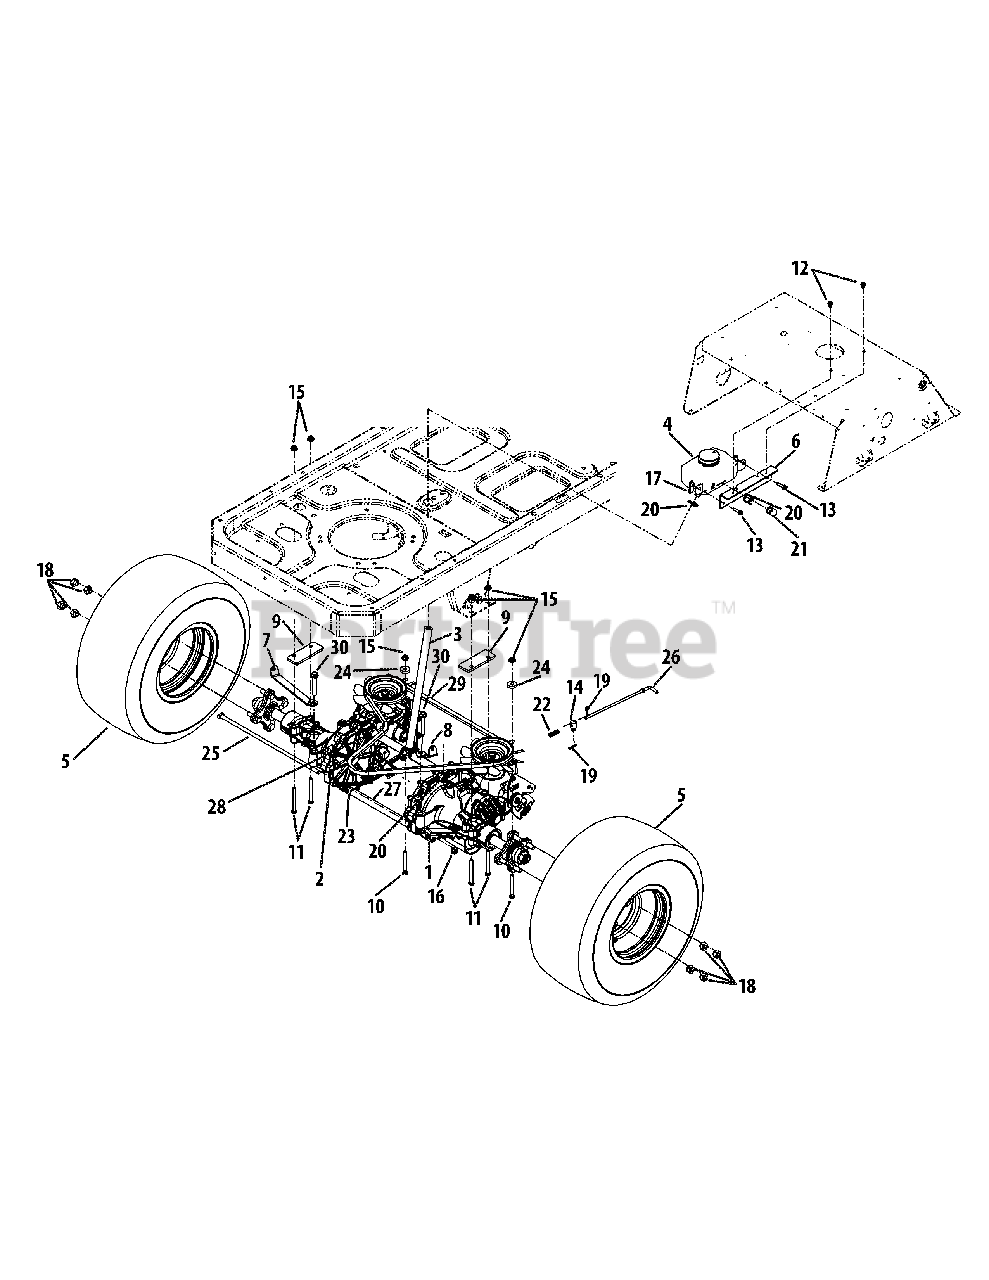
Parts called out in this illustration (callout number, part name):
1	Transmission Assembly (RH)
2	Transmission Assembly (LH)
4	Expansion Tank Assembly
5	Wheel Assembly, 20 x 10 x 8
5	Rim Assembly, 8.0 x 6.19 x 4
5	Tire, 20 x 10 x 8
5	Air Valve
6	Expansion Tank Bracket
7	Transmission Brace (LH)
8	Transmission Brace (RH)
9	Transmission Spacer
10	Hex Screw, 5/16-18 x 2.75
11	Hex Screw, 5/16-18 x 3.00
12	Screw, 1/4-20 x .500
13	Screw, 1/4-20 x 1.000
14	Ferrule, .325 x .312
15	Flange Lock Nut, 5/16-18
16	Flange Lock Nut, 3/8-16
17	Speed Nut, 1/4-20
18	Lug Nut, 7/16-14
19	Bow-Tie Cotter Pin
20	Hose Clamp, 1/2"
21	Cap, 1/2 x .870
22	Compression Spring, .405 x 1.17
23	Extension Spring, .545 x 4.555
24	Flat Washer, .35 x 1.0 x .2
25	Rod, .337 x 14.75
26	Bypass Rod
27	Tube, 7/16 x 3/4 x 11.3
28	Straight Fitting, 9/16 x 1/2
29	V-Type Belt
30	Hex Screw, 5/16-18 x 3.00
